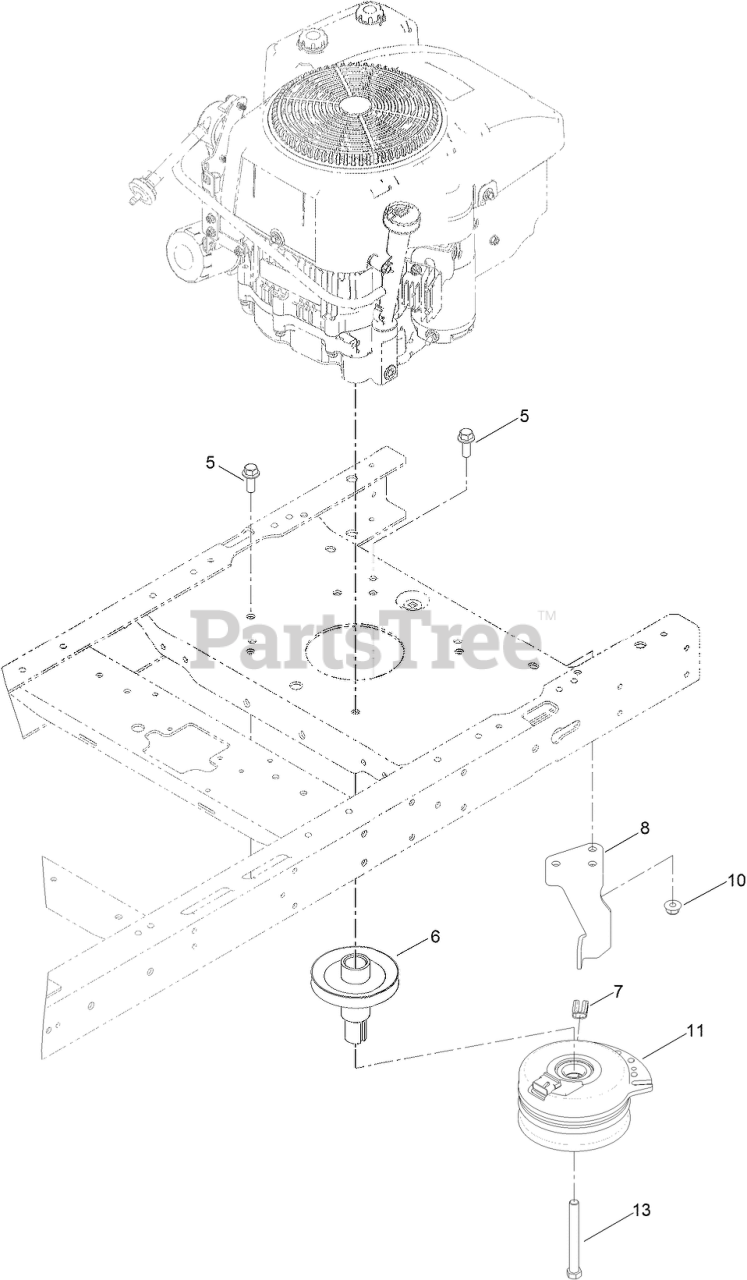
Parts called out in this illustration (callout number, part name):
5	SCREW-HHF
6	PULLEY-ENGINE
7	ISOLATOR-CLUTCH
8	STOP-CLUTCH
10	NUT-HF, NI
11	CLUTCH-ELECTRIC
13	SCREW-HH
